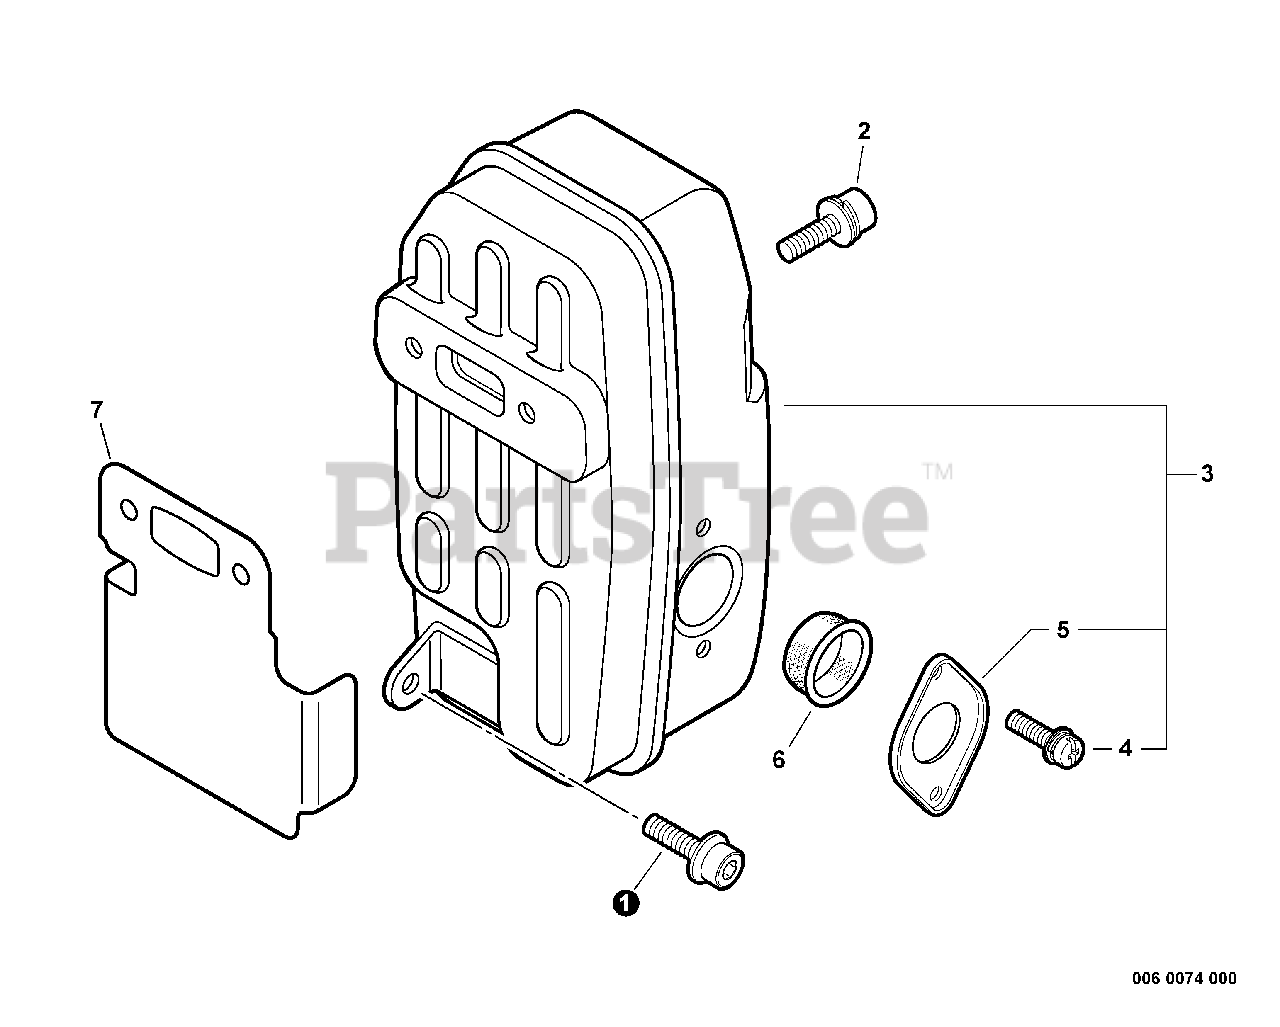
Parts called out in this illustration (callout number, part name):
1	BOLT 5×14
2	BOLT, FLANGE 6×20
3	MUFFLER ASSY
4	SCREW 4×10
5	GUIDE, EXHAUST
6	SCREEN, SPARK ARRESTER
7	HEAT SHIELD, EXHAUST
